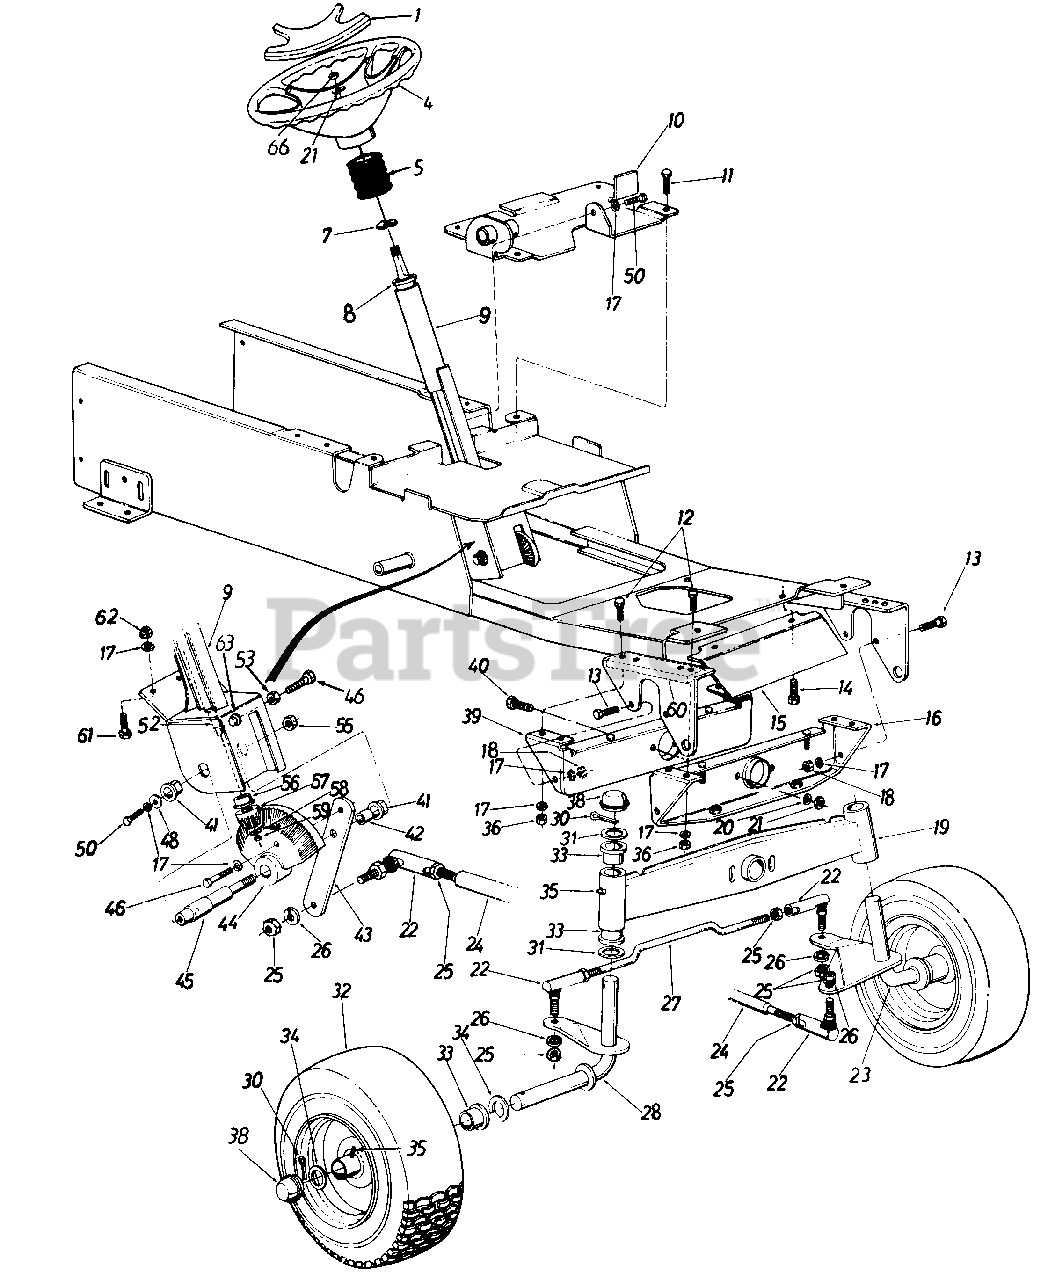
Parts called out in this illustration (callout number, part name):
1	Steering Wheel Cap
4	Steering Wheel
5	Steering Bellow
7	Wave Wash. .660" I.D. x .88" O.D.
8	Ball Brg. .63" I.D. x 1.38" O.D.
10	Dash Panel Base Plate Ass'y.
11	Hex Self-Tap Scr. 3/8-16 x .75" Lg.
12	Hex Bolt 3/8-16 x 1.50" Lg.
13	Hex Bolt 3/8-16 x 1.00" Lg.
14	Hex Wash. S.F. Tap Scr. 3/8-16 x 1.25" Lg.
15	Dust Shield
18	Hex Nut 3/8-16 Thd.
19	Pivot Bar Ass'y.
20	Bell-Wash. 3/8" I.D.
21	Hex Cent. L-Nut 3/8-16 Thd.
22	Drag Link End
23	Axle Ass'y. - L.H.
25	Hex Nut 1/2-20 Thd.
26	L-Wash. 1/2" I.D.
28	Axle Ass'y. - R.H.
30	Cotter Pin 3/16" Dia. x 1.50" Lg.
31	Fl-Wash. 1.00" I.D. x 1.62" O.D.
33	Flange Brg. 1" I.D.
34	Fl-Wash. 1" I.D. x 1.25" O.D.
35	Grease Fitting
36	Hex Nut 3/8-16 Thd.
38	Dust Cover
41	Flange Brg. w/Flats .753" I.D.
42	Steering Gear Shaft Spacer
43	Steering Arm
44	Bevel Gear
45	Steering Gear Shaft
46	Hex Bolt 3/8-16 x 1.50" Lg.
48	Fl-Wash. .406" I.D. x 1.25" O.D.
50	Hex Bolt 3/8-16 x .75" Lg.
52	Steering Shaft
53	Hex Jam Nut 3/8-16 Thd.
55	Hex Ins. L-Nut 1/2-20 Thd.
56	Hex Flange Brg. .630 I.D.
57	Pinion Gear
58	Fl-Wash. 3/8" Dia.
59	Hex Cent. L-Nut 5/16-24 Thd.
62	Hex Nut 3/8-24 Thd.
